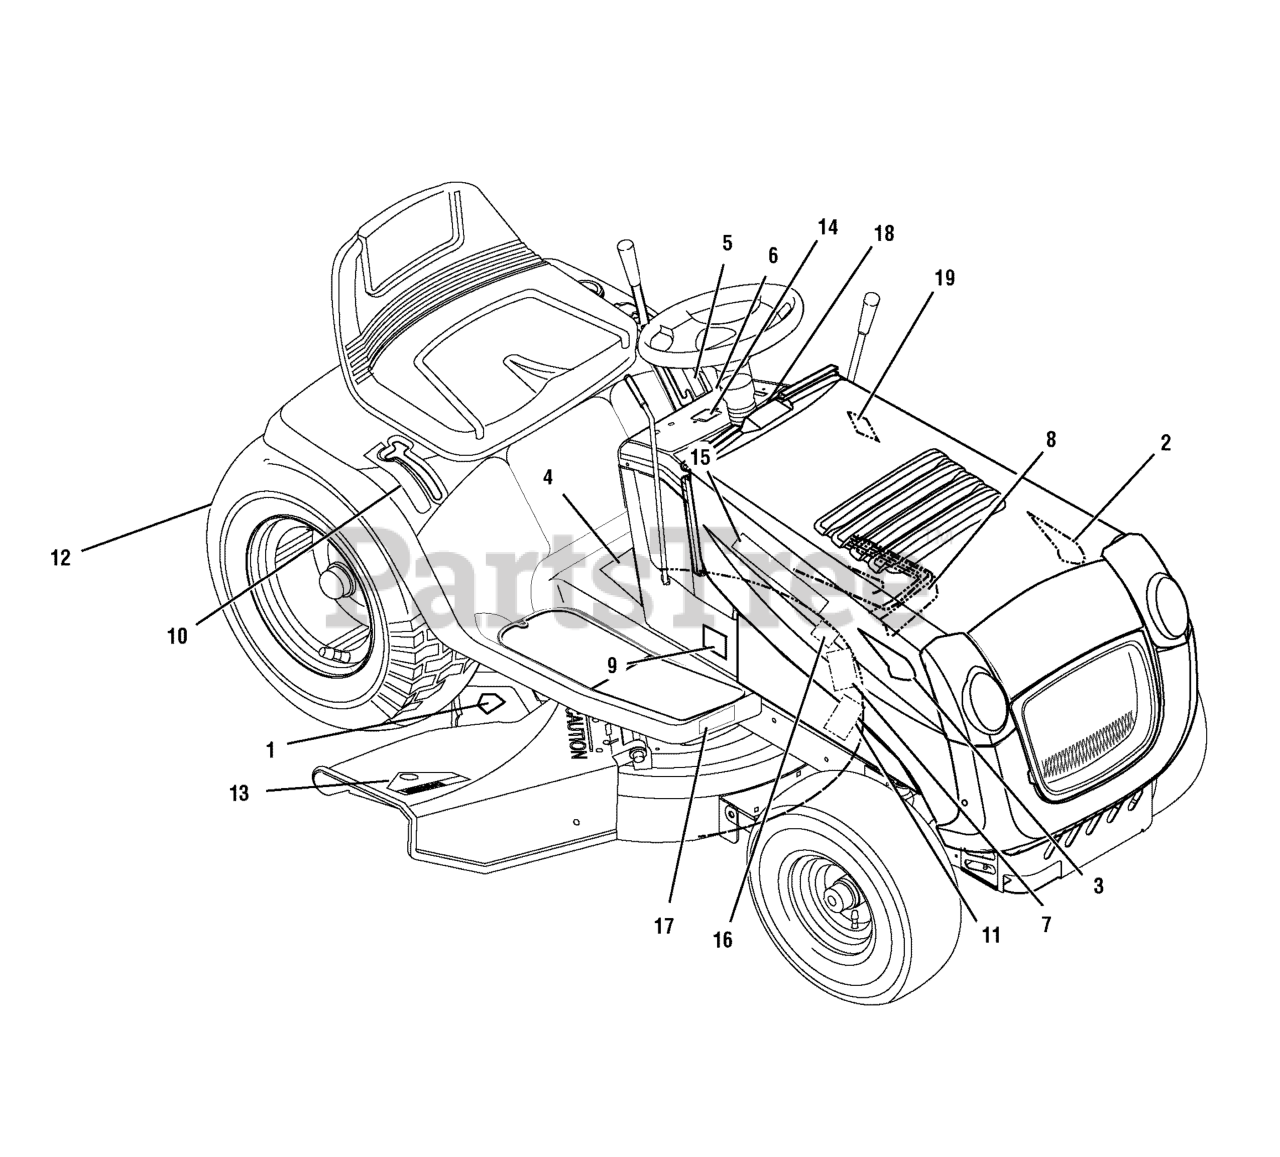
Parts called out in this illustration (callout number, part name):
1	DECAL, CUT FINGER SYMBOLS
2	DECAL, 12.5/38 LH
3	DECAL, 12.5/38 RH
4	DECAL, WARNING EXPORT
5	DECAL, 7 POS CUT HGT SM SD
6	DECAL, DECK LEVEL
7	DECAL, NO STEP EXPORT
8	DECAL, BRAKE/CLUTCH EXP
9	DECAL, Engage PTO
10	DECAL, 5 SPEED
11	DECAL, Warning, Muffler Area
12	DECAL, DRAWBAR WARNING PICT
13	DECAL, No Step Chute
14	DECAL, DASH/SYMBOLS W1
15	DECAL, SENTINEL R.H. & L.H.
16	DECAL, 3 Way Deck
17	DECAL, Cutting Height
18	DECAL, Gas Gauge
19	DECAL, No Step Chute
